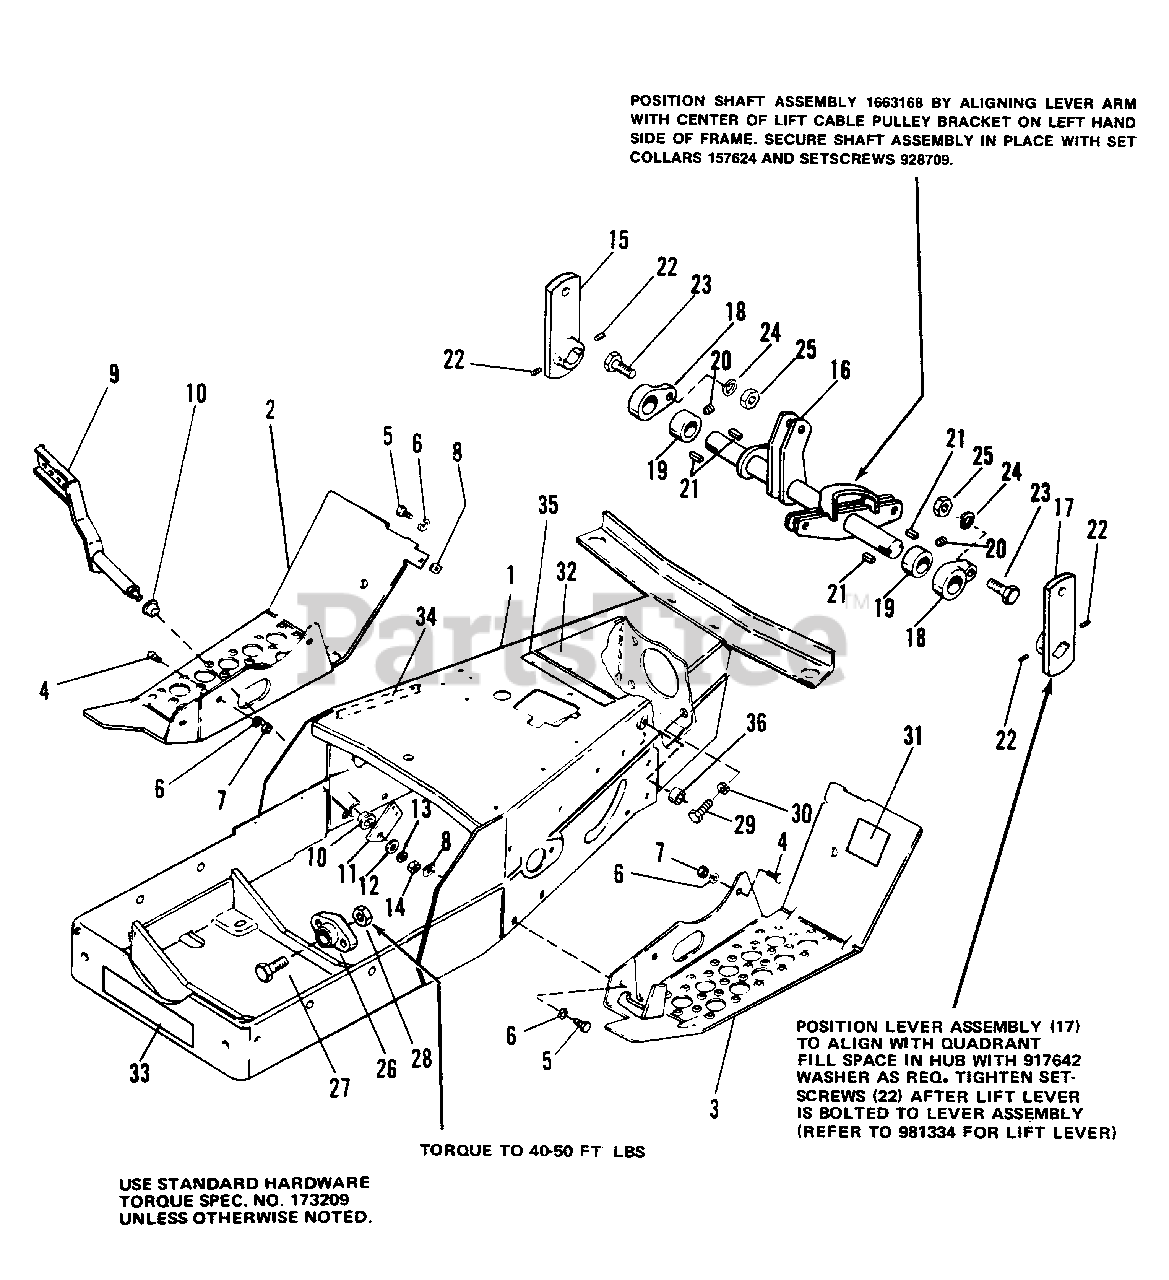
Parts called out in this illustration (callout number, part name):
1	REAR FRAME ASSEMBLY
2	FOOT REST, R.H.
3	FOOT REST, L.H.
4	BOLT, Carriage, 5/16-18 x 3/4
5	CAPSCREW, Hex Hd., 5/16-18 x 3/4
6	LOCKWASHER, 5/16
7	NUT, Hex, Full, 5/16-18
8	NUT, Speed, Tinn., 5/16-18
9	FOOT PEDAL ASSEMBLY
11	ARM, Pedal Foot
12	WASHER, 3/8
13	LOCKWASHER,3/8
14	NUT, Hex, Full, 3/8-16
15	FRONT LIFT LEVER ASSEMBLY
16	LIFT SHAFT ASSEMBLY
17	LIFT LEVER ASSEMBLY
18	BEARING, Lift Lever
19	SET, Collar
20	SETSCREW, Cup Pt., 5/16-18 x 3/8
22	SETSCREW, Soc. Hd., 5/16-18 x 1/4
23	CAPSCREW, Hex Hd., 5/16-18 x 1-1/4
24	LOCKWASHER, 5/16
25	NUT, Hex, Full, 5/16-18
26	BEARING, Pivot
27	CAPSCREW, Whiz, 3/8-16 x 1-1/4
28	NUT, Flange, 3/8-16
29	CAPSCREW, Hex Hd., 7/16-14 x 1-1/2
30	LOCKWASHER, 7/16
31	DECAL, Parking Brake
32	PLATE, Safety
33	DECAL, Simplicity
34	DECAL, Clutch
35	DECAL, Warning
